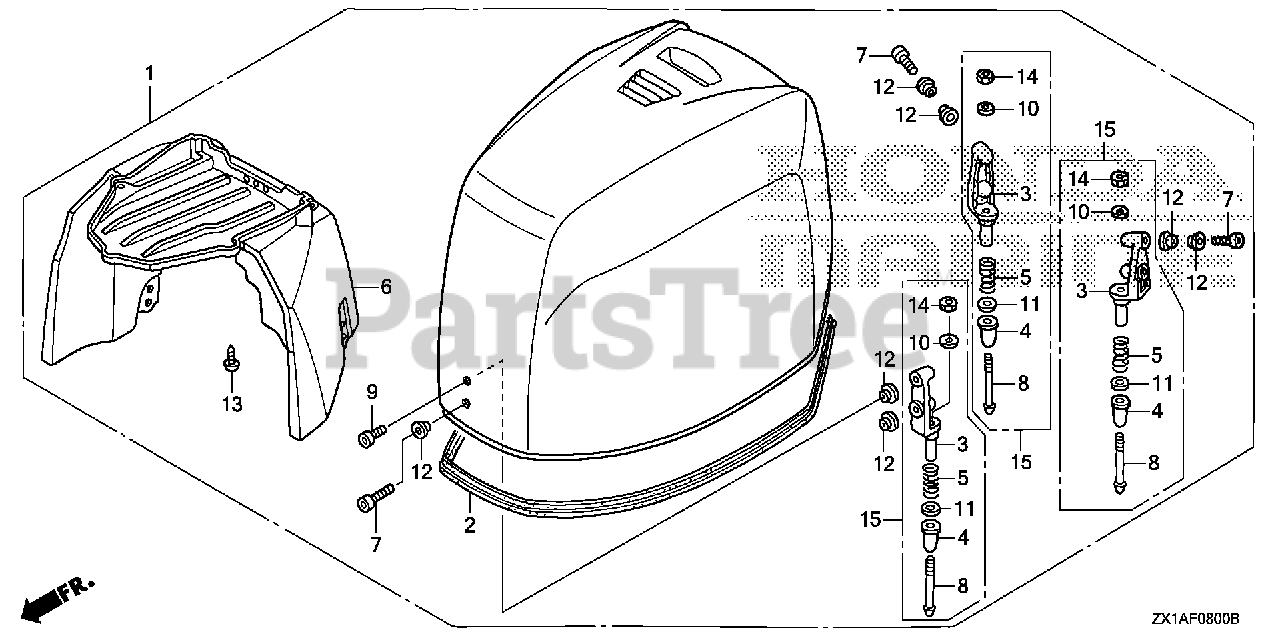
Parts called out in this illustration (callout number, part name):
1	COVER ASSY., ENGINE *NHB14M* (AQUA MARINE SILVER METALLIC)
1	COVER ASSY*NH565*
2	SEAL, ENGINE COVER
3	BRACKET, HOOK
4	DAMPER, HOOK
5	SPRING, LOCK ADJUSTER
6	GUIDE, ENGINE COVER AIR
7	BOLT, SOCKET (6X20)
8	BOLT, COVER LOCK
9	BOLT, SOCKET (6X16)
10	WASHER, PLAIN (6MM) Use from Frame SN 4800713.
11	WASHER, PLAIN (12MM)
12	COLLAR, DISTANCE (6.5X9X3)
13	SCREW, TAPPING (4X12)
14	NUT, HEX. (6MM)
15	HOOK KIT, COVER
